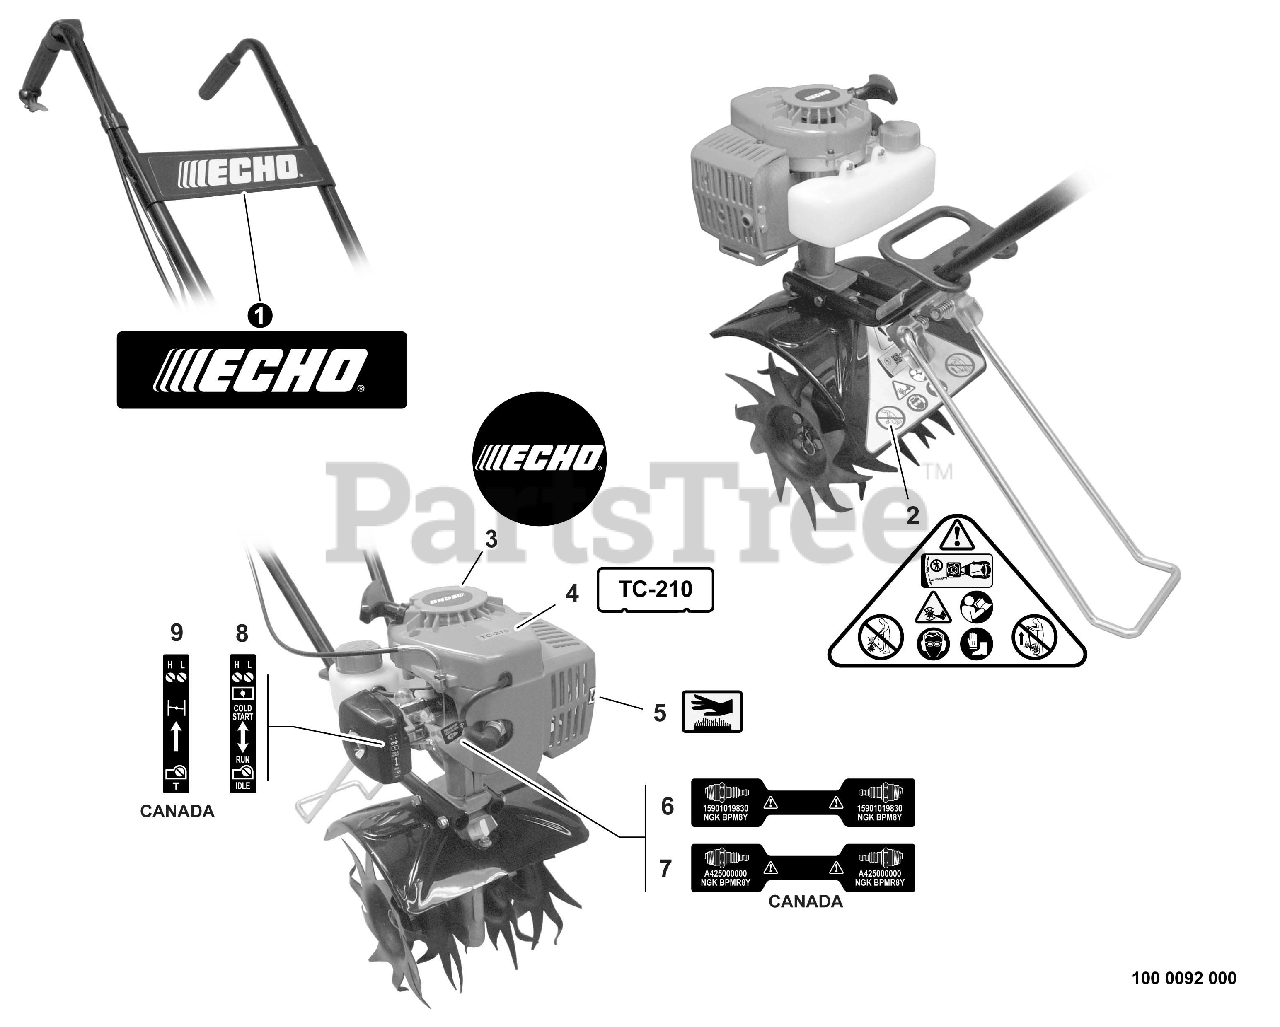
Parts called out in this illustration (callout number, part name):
1	LABEL - ECHO
2	LABEL - CAUTION
3	LABEL - ECHO
4	LABEL - MODEL TC-210
5	LABEL - HOT SURFACE
6	LABEL - SPARK PLUG -- BPM-8Y
7	LABEL - SPARK PLUG -- BPMR-8Y
8	LABEL - CHOKE
9	LABEL - CHOKE
